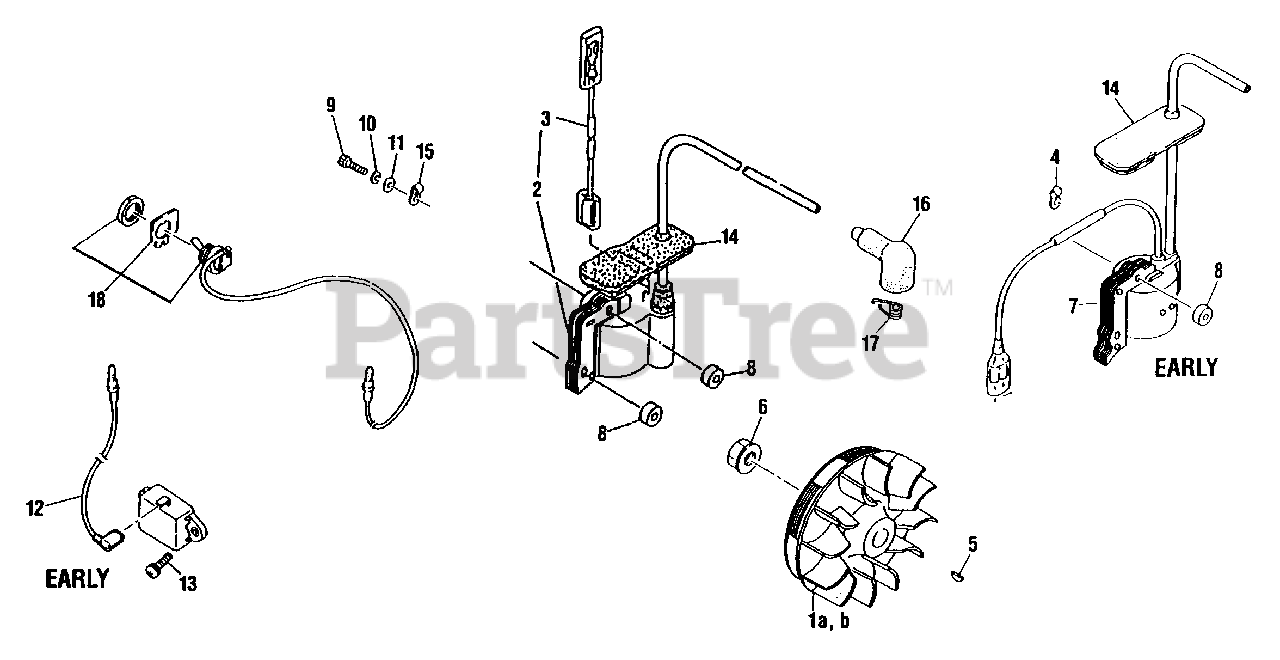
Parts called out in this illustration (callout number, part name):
1A	FLYWHEEL
1B	ROTOR ASSY
2	COIL
4	CLAMP
5	KEY, WOODRUFF - 3×10
6	NUT M8
7	COIL
8	INSULATOR 4.2×11×6
9	BOLT
10	WASHER, SPRING 4 MM
11	WASHER 4.3×9.6×0.8
12	WIRE
13	SCREW
14	GROMMET
15	CLAMP
16	CAP, SPARK PLUG
17	TERMINAL, SPARK PLUG
18	SWITCH
